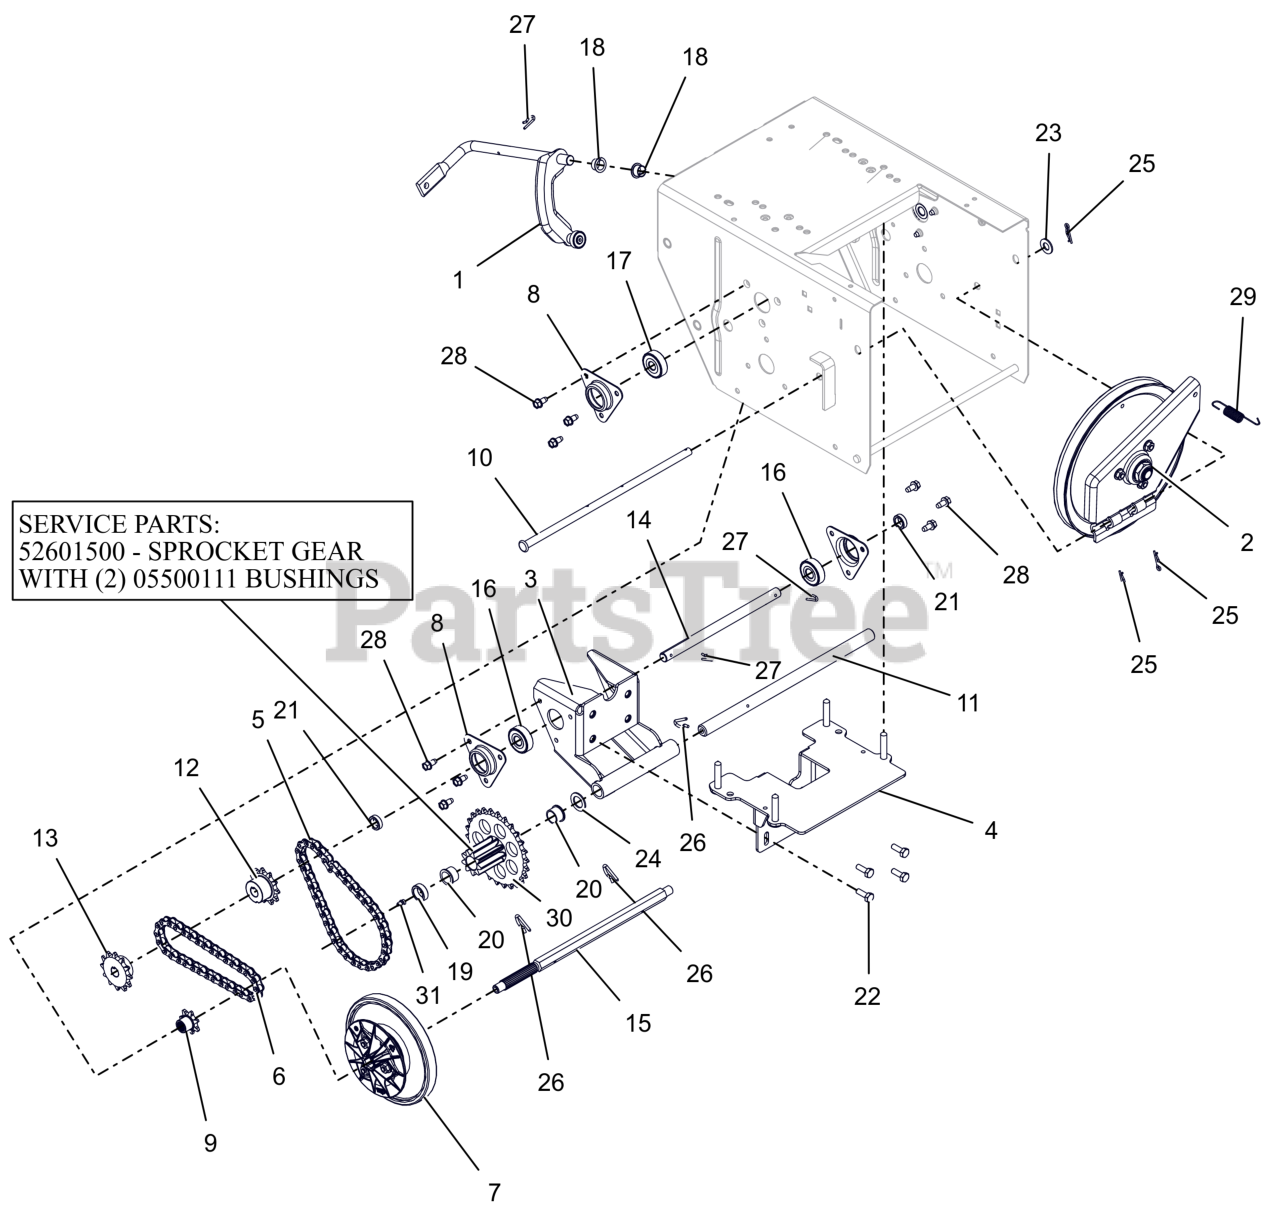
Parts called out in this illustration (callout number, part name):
1	ARM, SHIFT - ASSEMBLY
2	PLATE, SWING ASSEMBLY-DEEP
3	WLDMT, TRIPLE REDUCTION BRKT
4	STRAP, TRIPLE REDUCITON BOLT
5	CHAIN, ROLLER - #41X36 PITCHES
6	CHAIN - #41, 32 PITCHES
7	DISC, FRICTION DRIVE-ASSEMBLY
8	FLANGE, BEARING
9	SPROCKET, PINION 7T W/SPLINE
10	PIN, PIVOT
11	SHAFT, PINION-HARDENED
12	SPROCKET, 11 TOOTH
13	SPROCKET, 12 TOOTH
14	SHAFT, REDUCTION HEAT TREATED
15	SHAFT, HEX HEAT TREATED SPLINE
16	BRG-BALL .500X1.38X.437
17	BRG-BALL .437X1.375X.437
18	BUSHING, POLYLINER-.50 SPLIT
19	BSHG-SLV, .635X.880X.305
20	BSHG-FLG .625X.750X.500X.875
21	SPCR, SLV
22	BLT, HEX .25-20X.75 G5 ZCC
23	WSHR,FLT .406X.812X.065 ZCC
24	WSHR, FLT .630X1.005X.062 ZCC
25	PIN, HAIR #225 .072X1.09
26	PIN, SPRING CLIP
27	CLIP, SPRING
28	SCR-TAP .25-20X.50 HWH ZCC
29	SG-TENS .048X.50X2.8
30	PINION & SPROCKET
30	PINION & SPROCKET W/BUSHINGS
31	ZERK,FITTING .25X.125 DRIVE IN
